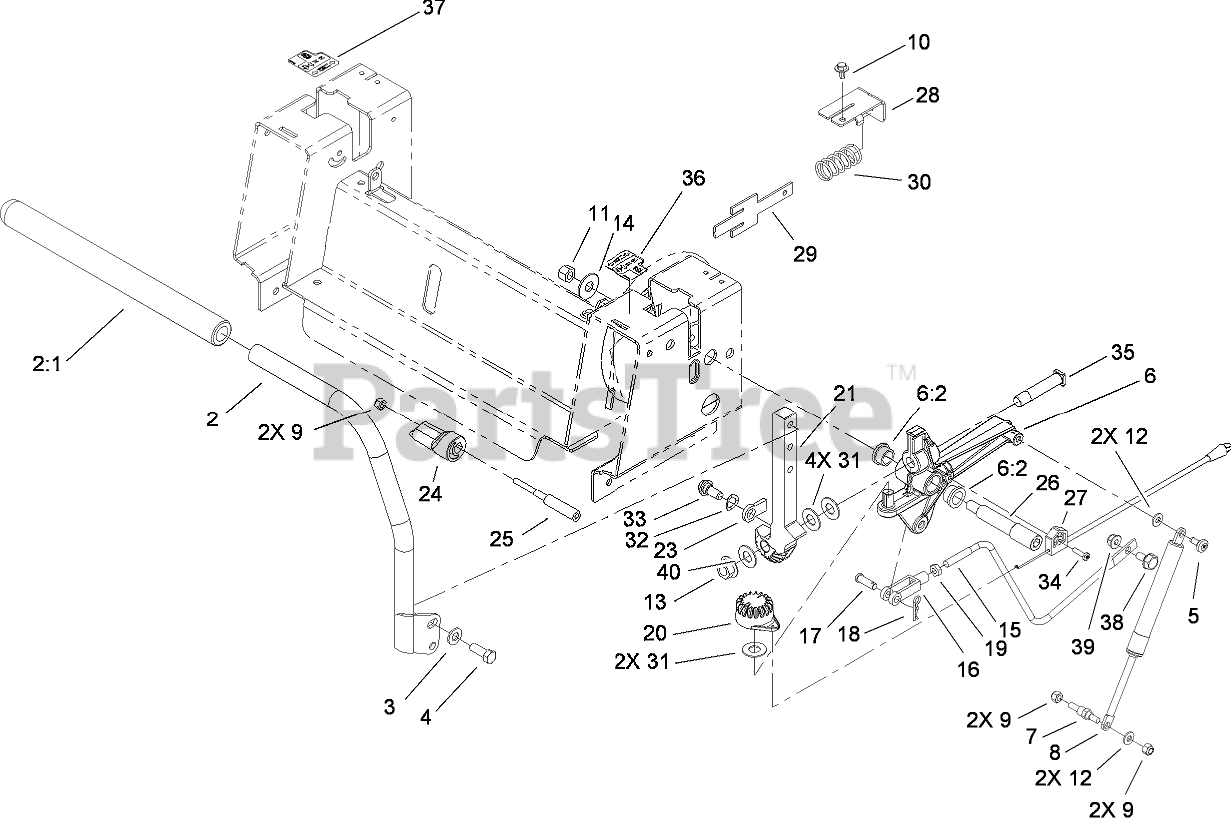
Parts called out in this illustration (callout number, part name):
2	LH HANDLE ASM
3	WASHER-FLAT
4	SCREW-HH
5	SCREW-SHOULDER
6	ACTIVATOR ARM ASM
6:2	BUSHING
7	STUD-DAMPER
8	Damper-Control, Motion
9	NUT-LOCK, NI
10	SCREW-HHFTF
11	NUT-LOCK, NI
12	WASHER-FLAT
13	NUT-HF
14	WASHER-FLAT
15	LINK-HYDRO
16	YOKE-ADJUSTABLE
17	PIN-CLEVIS
18	PIN-COTTER
19	NUT-JAM
20	GEAR-CONTROL
21	ARM-ACTUATOR, LH
23	TAB-STOP
24	ECCENTRIC
25	SCREW-ECCENTRIC
26	BOLT-SHOULDER
27	CABLE-BRAKE, PARKING
28	BRACKET-RETURN
29	PLATE-RETURN
30	SPRING-COMPRESSION
31	WASHER-PIVOT
32	WASHER-SPRING
33	BOLT-SHOULDER
34	SCREW-TORX
35	BOLT-SHOULDER
36	DECAL-CONTROL LEVER, LH
37	DECAL-CONTROL LEVER, RH
38	BOLT-SHOULDER
39	NUT-HF, NI
40	WASHER-TEFLON
